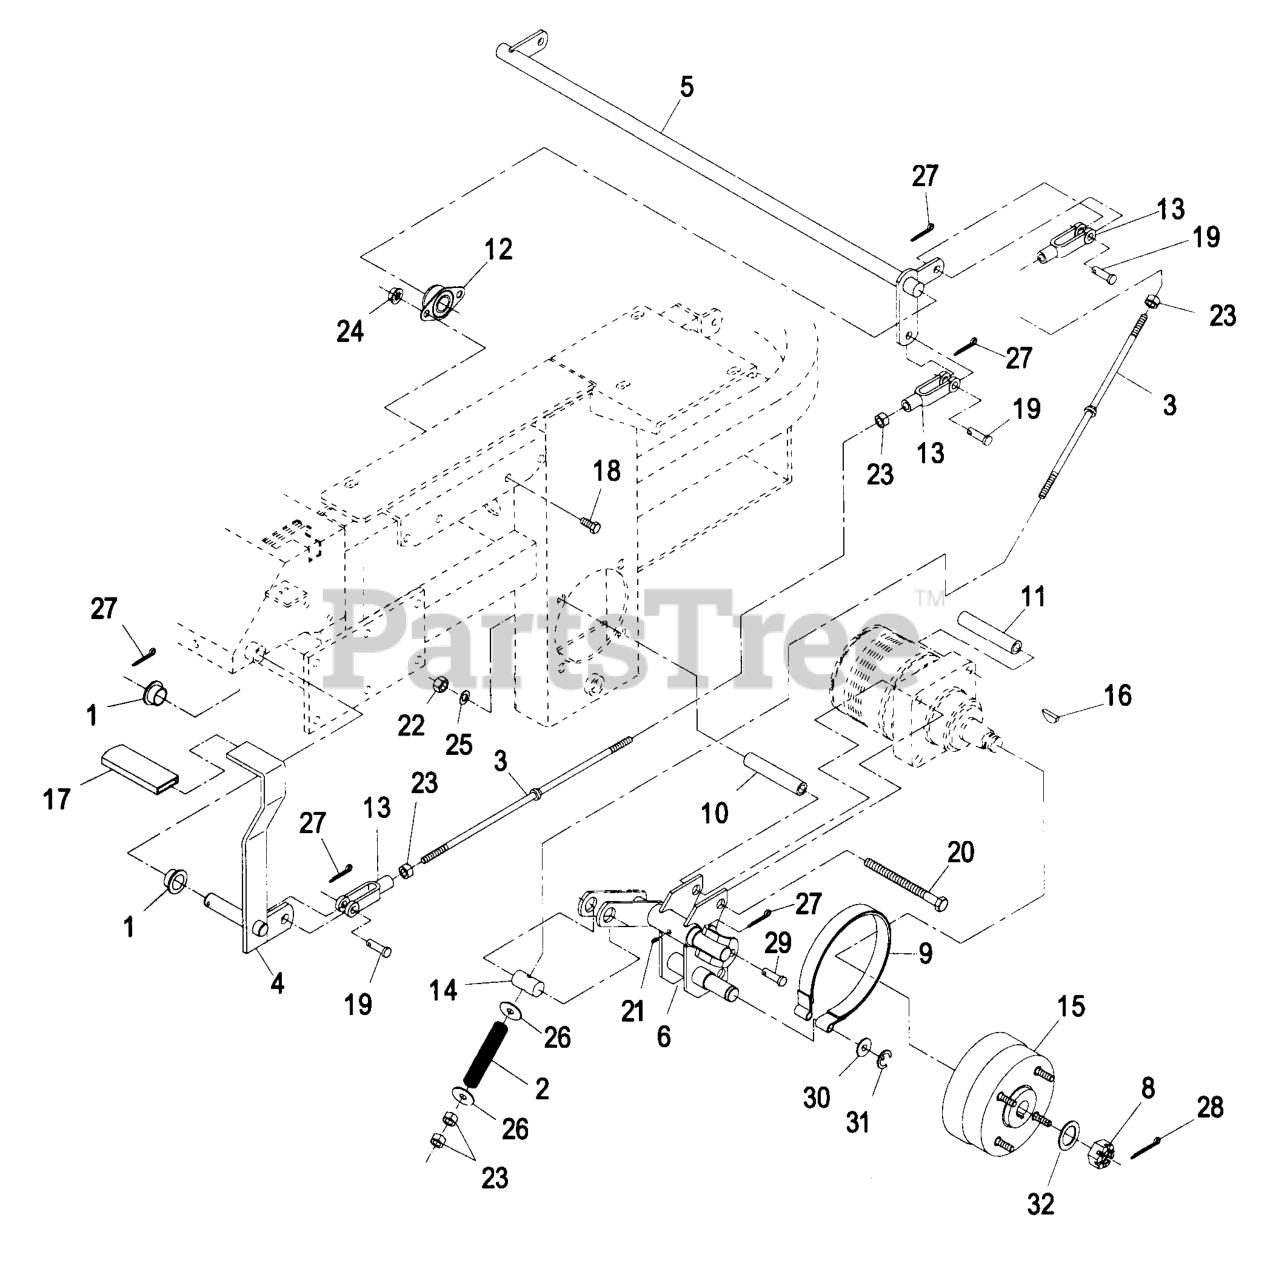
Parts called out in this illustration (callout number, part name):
1	BEARING-CONTROL
2	SPRING-BRAKE
3	ROD-BRAKE
4	BRAKE LEVER ASM
5	SHAFT-BRAKE
6	WLD,BRACKET LH 52
9	BAND,BRAKE
10	SPACER-WHEEL, SHORT
11	SPACER-WHEEL, LONG
12	BEARING-FLANGE, SIDE
13	YOKE-LINKAGE, BRAKE
14	PIN-TRUNION
17	GRIP-LEVER
19	PIN-CLEVIS
21	1481
28	PIN-COTTER
29	PIN,CLEVIS 3/8X2
32	WASHER-SPACER
